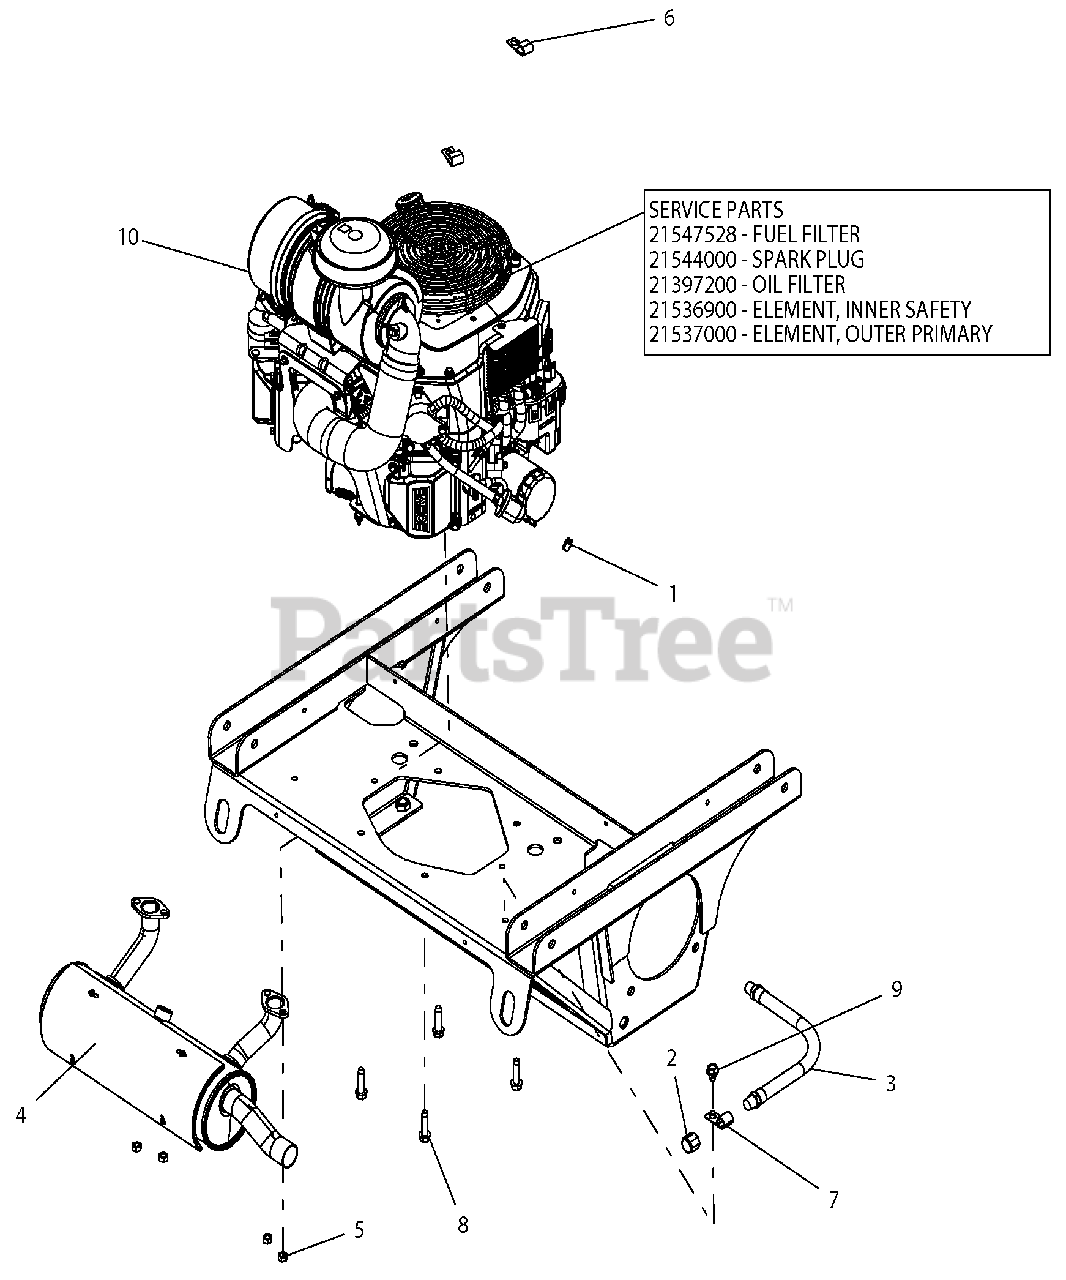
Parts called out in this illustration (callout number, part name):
1	CLAMP, FUEL LINE
2	PIPE, CAP 3/8 NPT FEMALE
3	HOSE, HYD .38-11-OK M6N0-M6N0
4	MUFFLER, KOHLER EFI
5	NUT-LK-TOP M8-1.25 YWZC
6	CLAMP, J
8	SCR-TAP .38-16X1.50 HWH TR YZ
9	SCR-TAP .38-16X.50 HWH TR YWZ
10	ENGINE, KOHLER EFI ECV749
